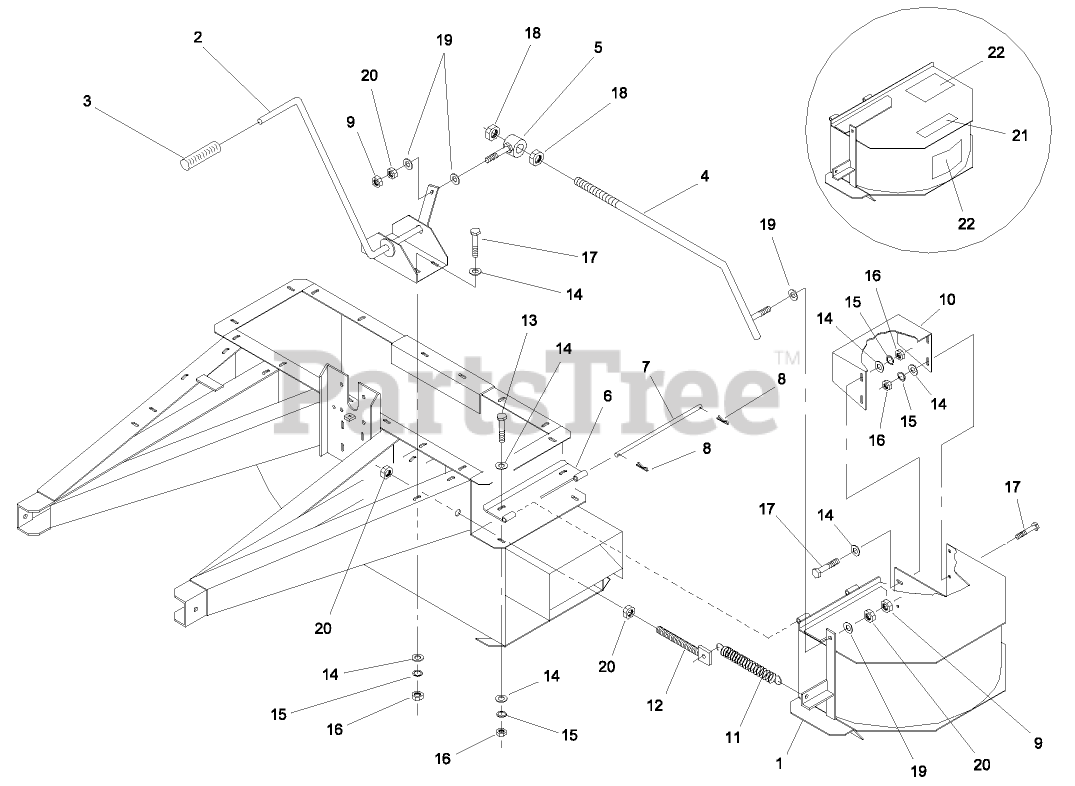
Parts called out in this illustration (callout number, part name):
1	AIR REVERSE ASSY
2	LIFT HANDLE ASY
3	HANDLE-GRIP
4	LIFT ARM ASY
5	REEL LIFT TUBE WA
6	HINGE ASSEMBLY
7	HINGE PIN PPL
8	PIN-COTTER
9	NUT-JAM
10	REVERSE AIR DEFLECTOR
11	Spring
12	SPRING LUG
13	SCREW-HH
14	WASHER-FLAT
15	WASHER-LOCK
16	NUT-HEX
17	SCREW-HH
18	NUT-HEX
19	WASHER-FLAT
20	NUT-HH
21	DECAL- NO RIDERS
22	DECAL - AIR DEFLECTOR
